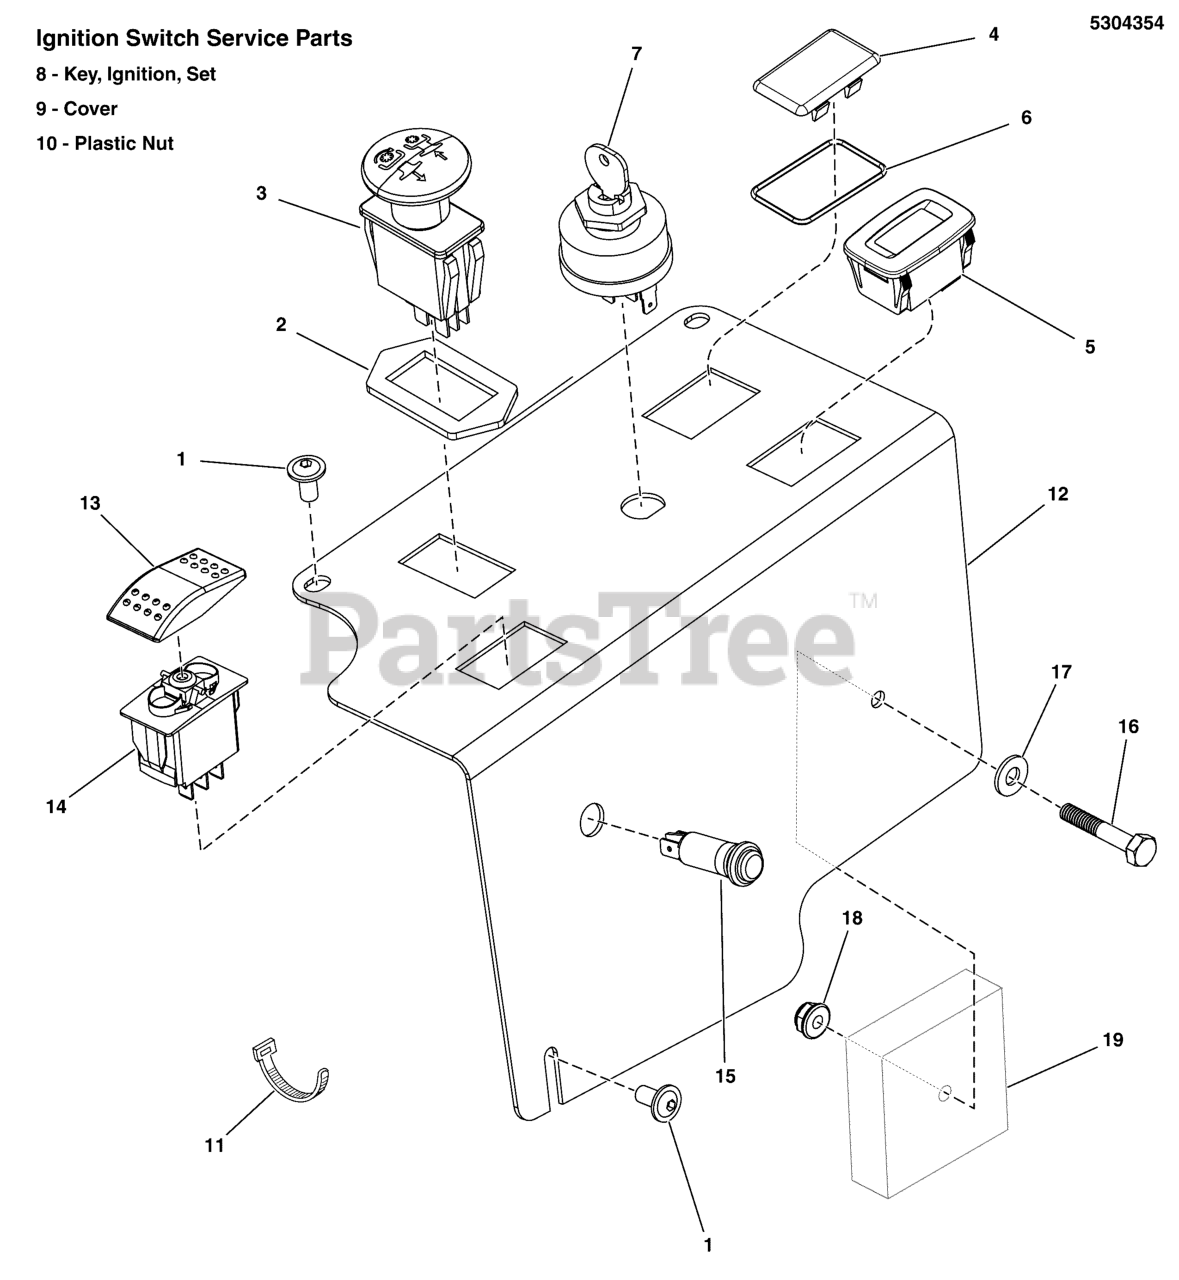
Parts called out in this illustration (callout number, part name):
1	SCREW, ALLEN HEAD 1/4-20X.500 ZINC PHOS
2	RING, SWITCH RETAINER
3	SWITCH, BLADE ENGAGEMENT
4	PLUG, .820X1.44 HOLE, BLACK PLASTIC
5	* HOUR METER, ASSEMBLE
6	O-RING, 7/8 ID X 1/16 W
7	SWITCH, IGNITION, 6 POST
8	KEY, IGNITION MOLDED SET
9	COVER, PLASTIC, SNAP ON
10	PLASTIC NUT
11	TIE,SELF-LOCKING, 6"
12	PLATE, CONTROL PANEL, S125XT,KAV EFI - BLK
13	ACTUATOR, ROCKER SWITCH, RED
14	BODY, ROCKER SWITCH
15	LIGHT, INDICATOR, PANEL, LED, RED
16	BOLT, 1/4-20 X 1-1/2 GD5 CZ
17	WASHER, 1/4 SAE
18	NUT, 1/4-20 HEX NYLOCK FLANGE
19	MODULE, THROTTLE CONTROL (SEE ELECTRICAL GROUP - KAWASAKI FUEL INJECTED MODELS)
